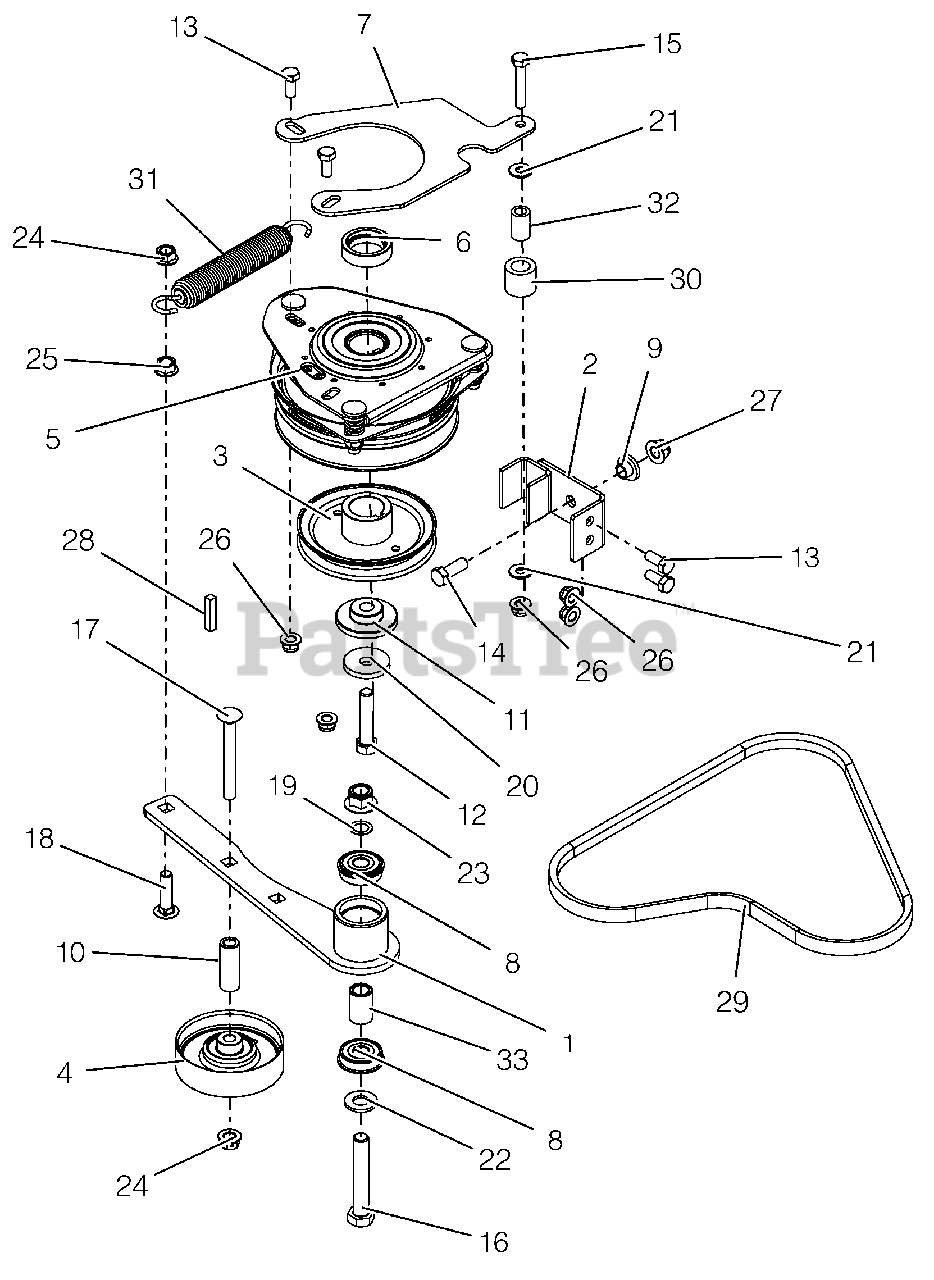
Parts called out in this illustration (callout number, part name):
1	WLDMT, HYDRO DRIVE IDLER ARME
2	WLDMT, CLUTCH STOP
3	SHEAVE, ENGINE 4.50 X 1.127
4	IDLER, FLAT 3.5" NO FLANGES
5	CLUTCH, OGURA GT1A-AR03
6	SPCR, CLUTCH
7	PLATE, CLUTCH DOG
8	BRG-BALL .50X1.38X.438 SEALED
9	BSHG-FLG .385X.500X.875X.406
10	BSHG, SLV .375 X .75 X 1.75
11	BSHG-FLG .469X1.06X.574X2.0
12	BLT-HEX .438-20X2 G8YZ NYTORQ
13	@BLT-HEX .31-18X.75 GR5 YWZC
14	@BLT-HEX .38-16X1.00 GR5 YWZC
15	@BLT-HEX .31-18X1.75 GR5 YWZC
16	@BLT-HEX .50-13X3.00 GR5 YWZC
17	BLT-RDHDSQNK .38-16X3.25 GR5YZ
18	@BLT-RDHDSQNK .38-16X1.50 G5YZ
19	WASHER, .500X.750X.020 THRUST
20	WASHER, 7/16" SPRING DISK
21	@WSHR-FL-STL.312X.734X.065 YWZ
22	@WSHR-FL-STL.531X1.06X.095YWZC
23	@NUT-LK-NYL-FLG .50-13 YWZC
24	NUT-LK-CTR-FLG .38-16 YWZC
25	@NUT-SPNLK-FLG .375-16 YWZC
26	@NUT-LK-NYL-FLG .31-18 YWZC
27	@NUT-LK-NYL-FLG .38-16 YWZC
28	KEY-SQ .25 X 1.25 X .25 SAE
29	BELT, 4L RAW EDGE 37.900"
30	BUMPER,RUBBER .62X1.0X.88 LG
31	SPRING, EXTENSION 1.0 X 6.65
32	BUSH.,S.391X.622X.950 ST
33	SPACER .510 X .75 X 1.1485
